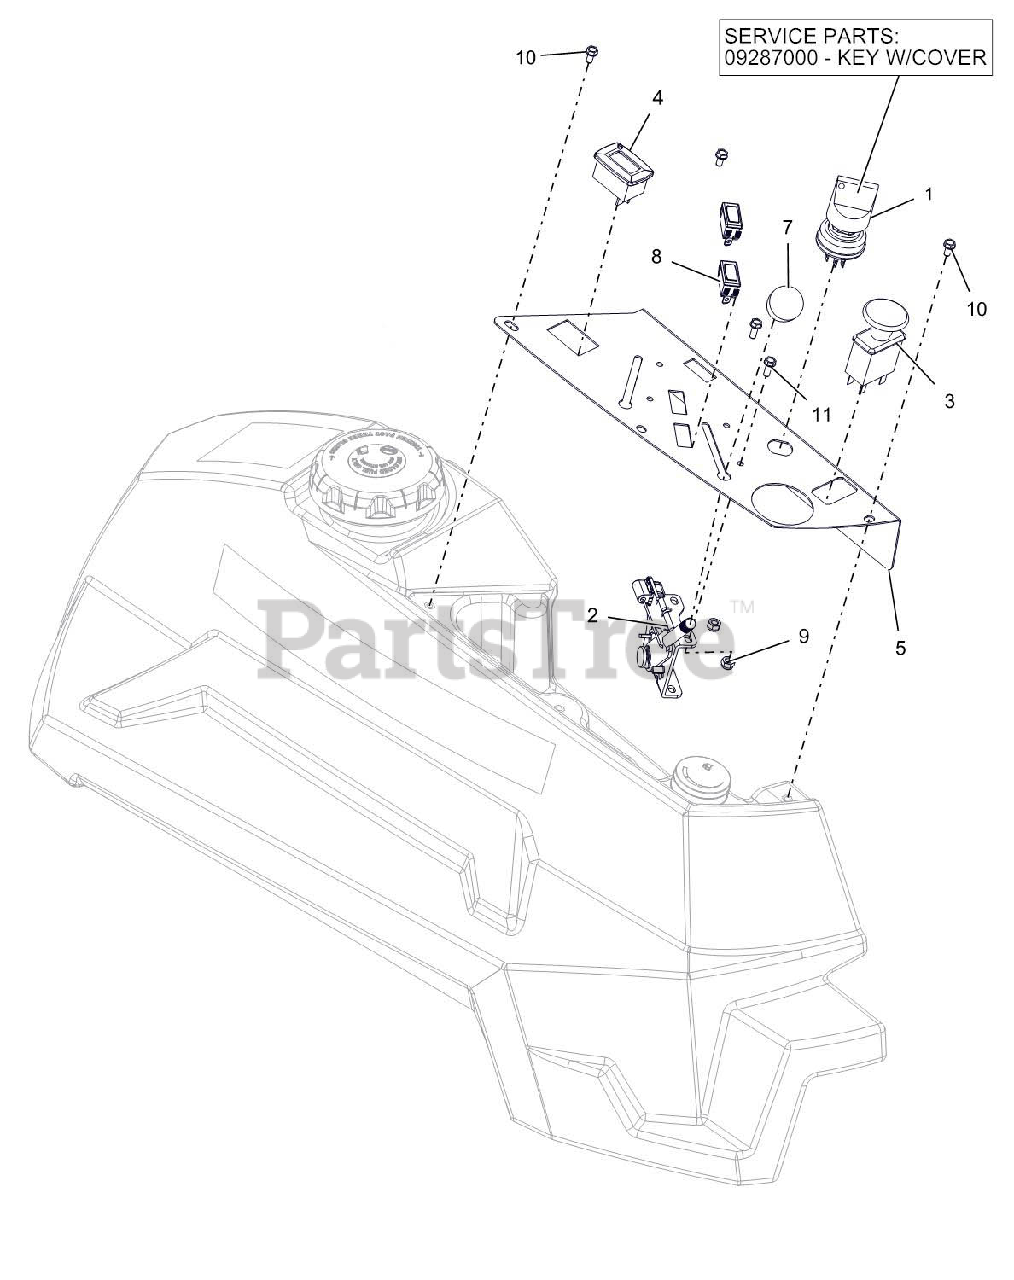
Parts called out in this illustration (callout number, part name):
1	KEY, W/ SHIELD
1	SWITCH, IGNITION
2	CABLE, PRO-CTRL 35.50"
3	SWITCH, CLUTCH
4	METER, HOUR W/MAINTENANCE
5	PT400 CONTROL PANEL - RED
7	KNOB-CONTROL-BLACK .38-16X.50
8	LIGHT,INDICATOR
9	@NUT-LK-NYL 10-24 W/INSRT YWZC
10	SCR-MCH 10-24X.38 HWHSTAINLESS
11	@SCR-MCH 10-24X.50 HWH YWZC
